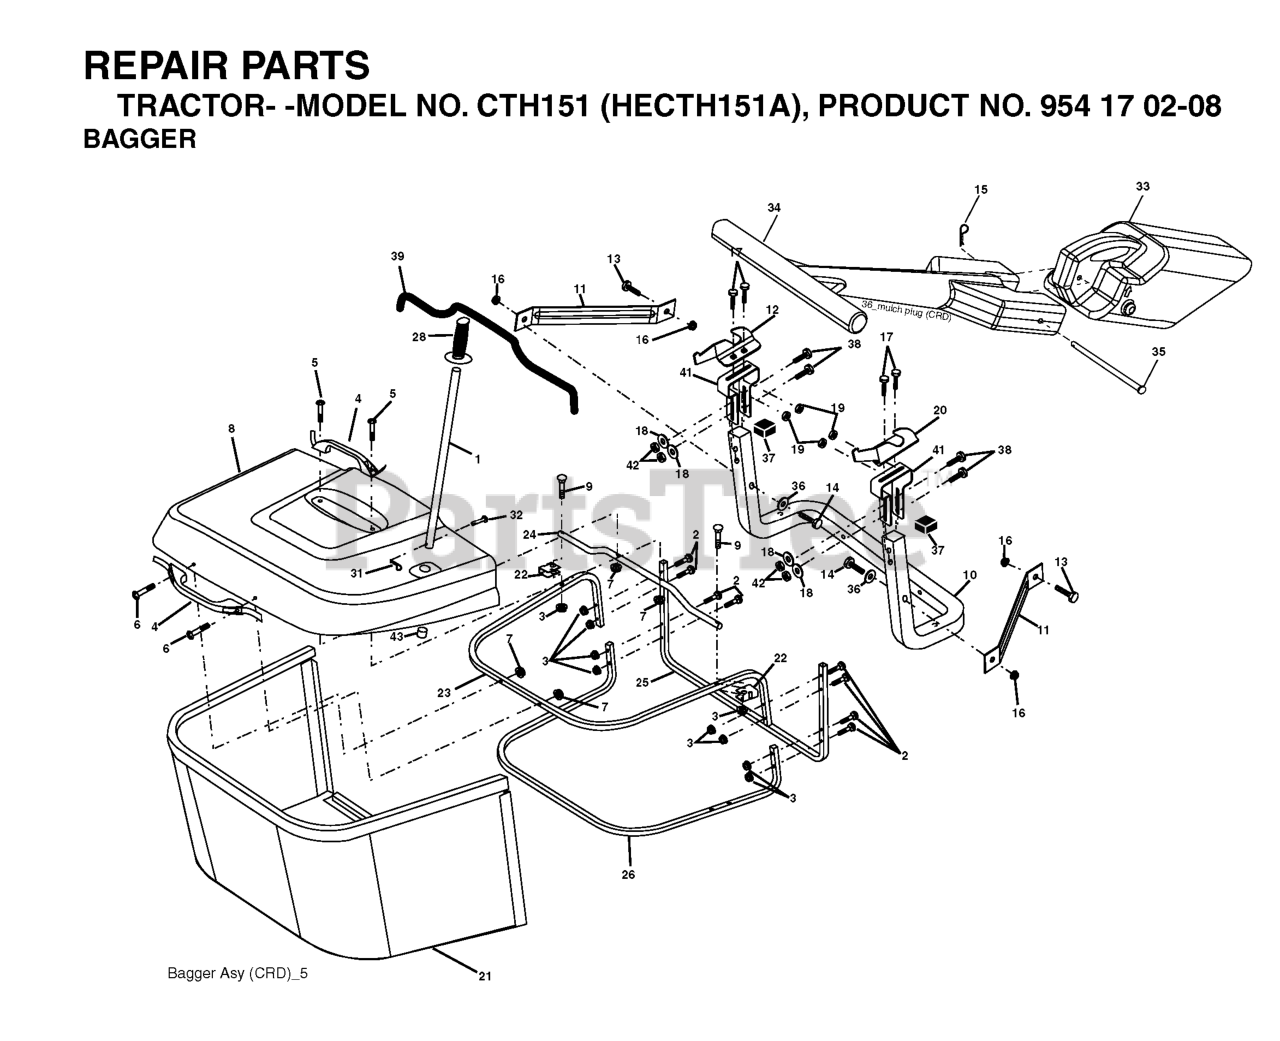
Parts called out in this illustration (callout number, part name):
1	TUBE HANDLE
2	Bolt Carriage 1/4-20 x 2.0 Gr.5
3	NUT T
4	HANDLE.BAGGER.W/LVRS.BLK.CRD
5	SCREW.PAN.HEAD
6	REPL BY 532 75 00-29
8	COVER.PNT.BGR.CRD.WSLOTS.MS668
9	Bolt Carriage 1/4-20 x 2.25d x Gr.5
10	TUBE
11	BRACKET.SUPPORT.UPPER.BAG.CRD
14	BOLT-HEX EAK
15	RETAINER-SPRNG RB
16	NUT LOCK FLG 3/8-16 UNC
17	RP BOLT 5/16-18 X3/4 ZN/YEL GR
18	WASHER M
19	NUT LOCK HEX FLANGE 5/16-18
20	BRACKET
21	GRASS BAG
22	BRKT.SIDE.BAG.CRD
23	TUBE.UPPER.BAG.CRD
24	TUBE.PIVOT.BAG.CRD.BLACK
26	TUBE.LOWER.BAG.CRD
28	GRIP.HANDLE.BLACK
31	RETAINER CLIP
32	RIVET,DRILLED
33	PLUG.MULCHER.92 CRD
34	HANDLE.MULCHER.92.CRD (2 2)
36	WASHER
37	Plug Support Bagger CRD
38	BOLT.5/16-18X2.5
39	SEAL.TRIM.37'
41	BRKT.VERT.ADJ.BAGGER.CRD
42	NUT.71038.31-18.HEX.NYLOCK
43	PLUG, TUBING END
